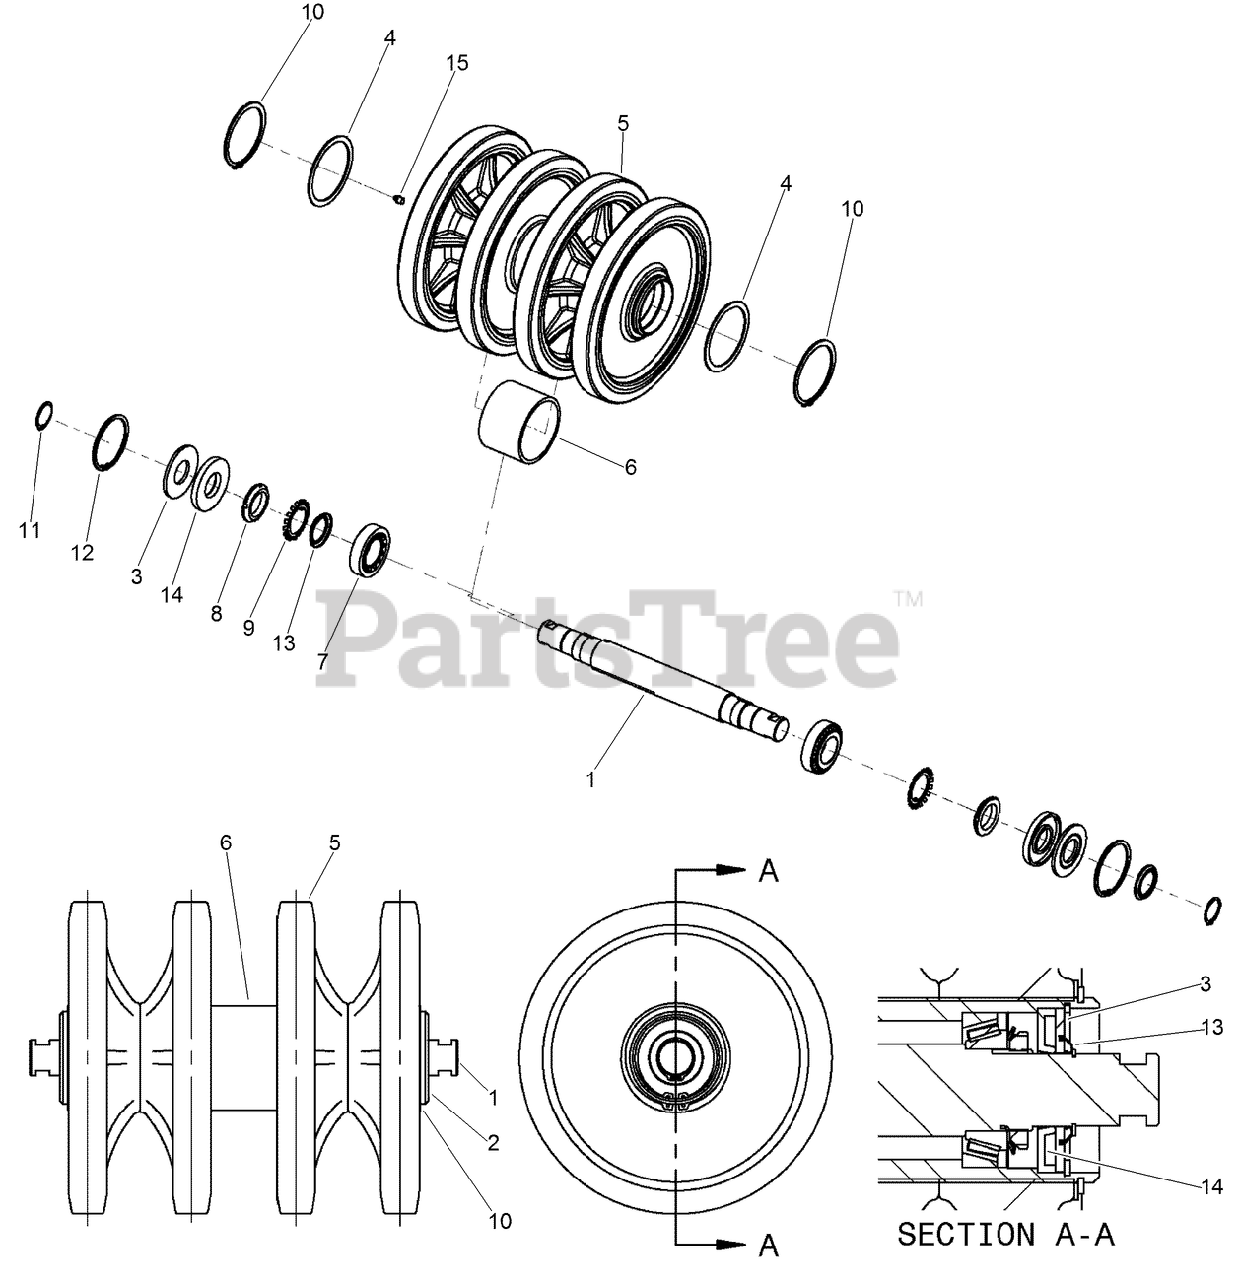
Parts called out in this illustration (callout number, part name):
1	AXLE - Track Roller
2	TUBING - Axle
3	SEAL - Double Lip
4	RING-RETAING, TRACK WHEEL
5	WHEEL - Moulded
6	Spacer
7	BEARING - Track Axle
8	NUT-GROOVED, M45
9	WASHER-LOCK, TABBED, M45
10	RING-RETAINING,EXTERNAL 4IN
11	RING-EX, RT
12	RING - Retaining, Internal
13	SEAL-OIL, DOUBLE LIP, 58MM OD
14	SEAL - Oil, 40 mm ID x 90 mm OD x 10 mm
15	FITTING-Lube 1/8-27 Dryseal PTF
